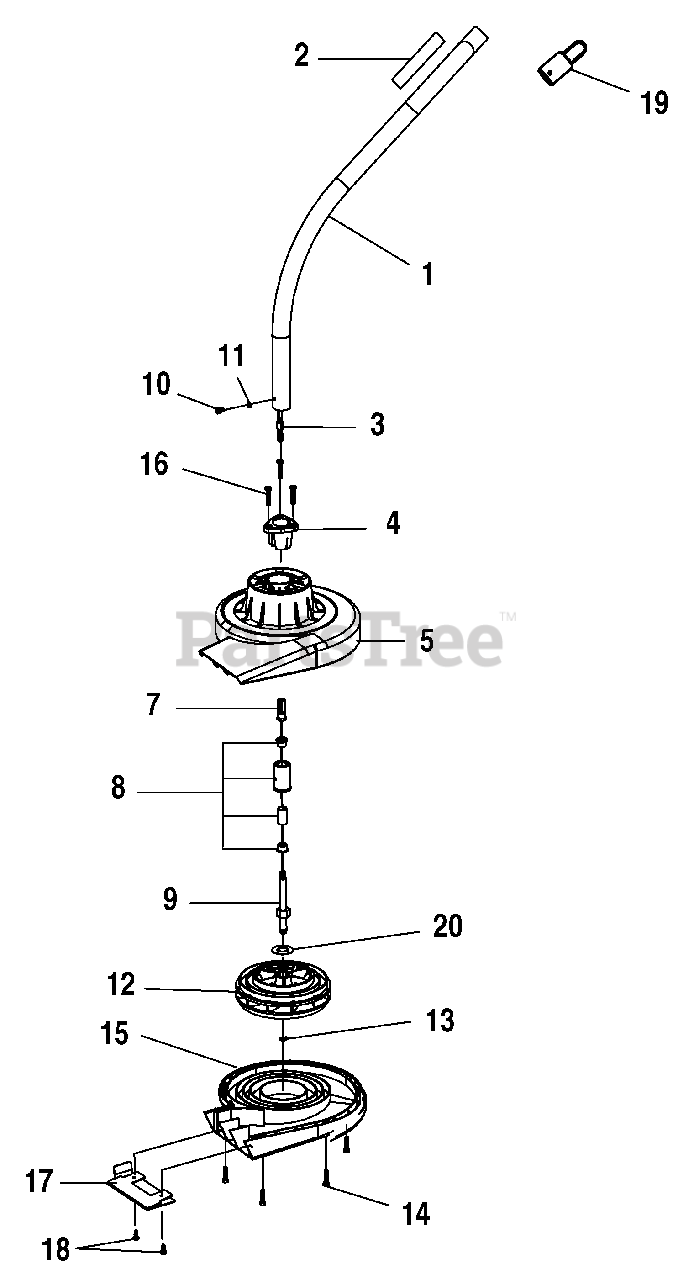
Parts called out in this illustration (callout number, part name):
1	DRIVE SHAFT HOUSING ASSEMBLY (UT15519B and UT15519D)
2	WARNING LABEL (UT15519B and UT15519D)
3	DRIVE SHAFT (UT15519B and UT15519D)
4	CLAMP (UT15519B and UT15519D)
5	UPPER HOUSING (UT15519B and UT15519D)
7	ARBOR ADAPTER (UT15519D)
8	BUSHING (UT15519D)
9	ARBOR SHAFT (UT15519D)
10	SCREW (M5 x 6 mm ) (UT15519D)
11	LOCK WASHER (UT15519D)
12	IMPELLER (UT15519B and UT15519D)
13	RETAINING RING (UT15519D)
14	SCREW (M4.2 x 19 mm) (UT15519D)
15	LOWER HOUSING (UT15519B and UT15519D)
16	SCREW (M4.8 x 26 mm T.F.) (UT15519D)
17	LOWER HOUSING GUARD (UT15519B and UT15519D)
18	SCREW (M4.2 x 12 mm) (UT15519D)
19	HANGER CAP (UT15519B and UT15519D)
20	WASHER (UT15519D)
